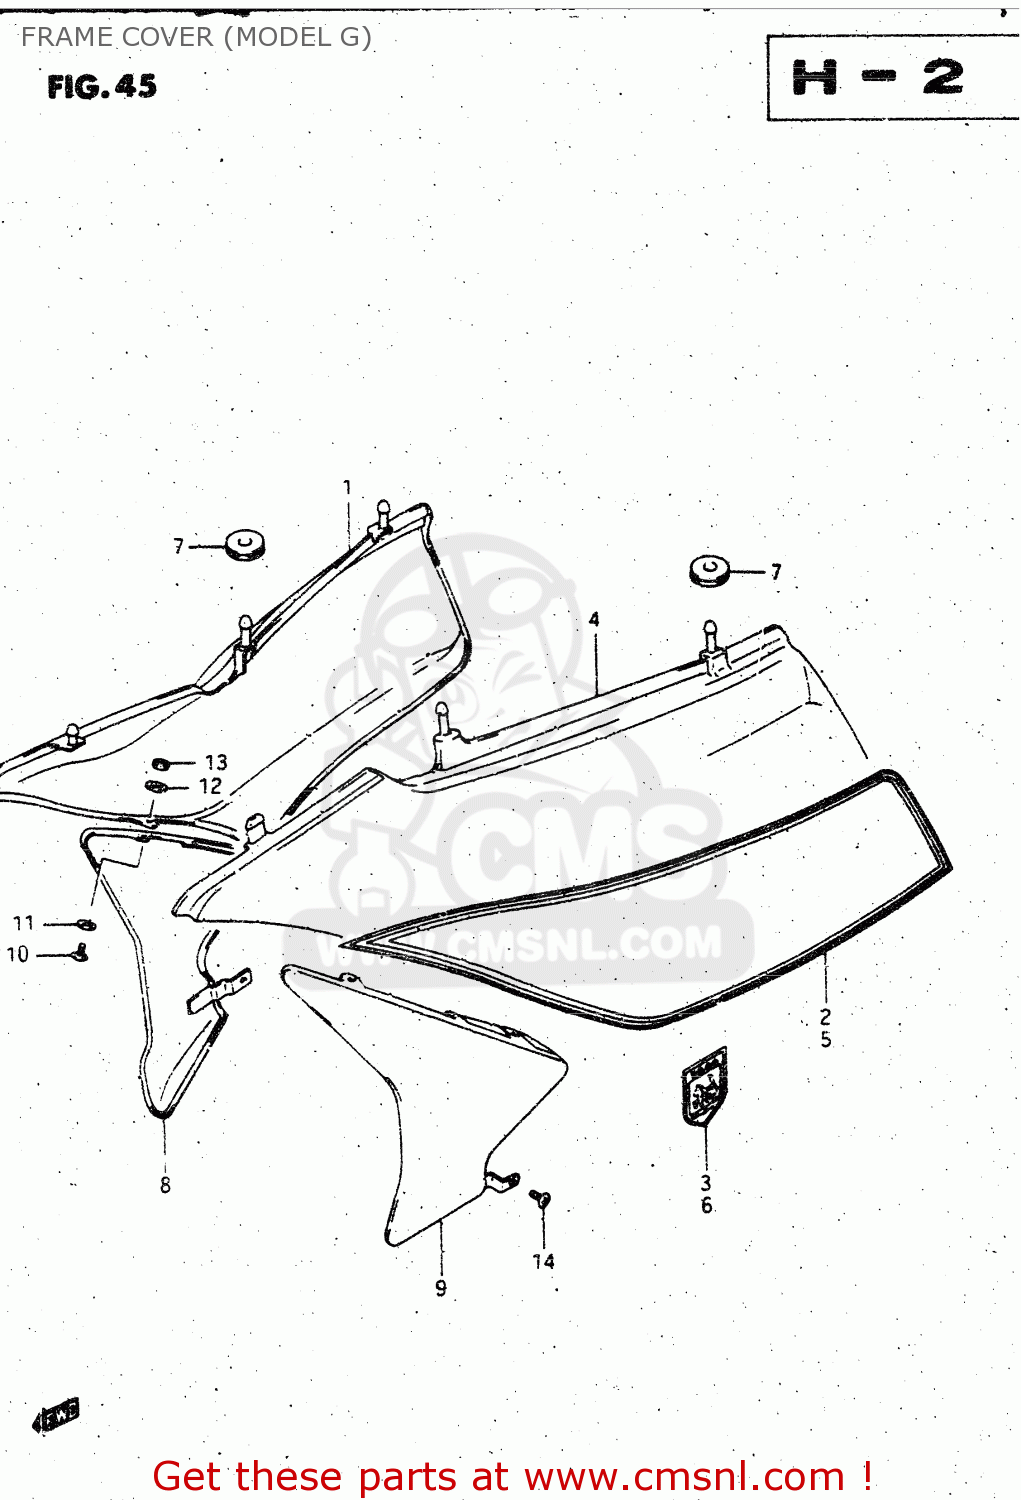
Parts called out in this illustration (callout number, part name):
1	COVER,FRAME,RIGHT
2	TAPE SET,FRAME COVER,RIGHT
3	EMBLEM,FRAME COVER
4	COVER,FRAME,LEFT
5	TAPE SET,FRAME COVER
6	EMBLEM,FRAME COVER
7	CUSHION
8	COVER,UNDER,RIGHT
9	COVER,UNDER,LEFT
10	SCREW
11	WASHER, LOWER
12	WASHER (6.7X16X1.8)
13	NUT 6MM
14	SCREW
